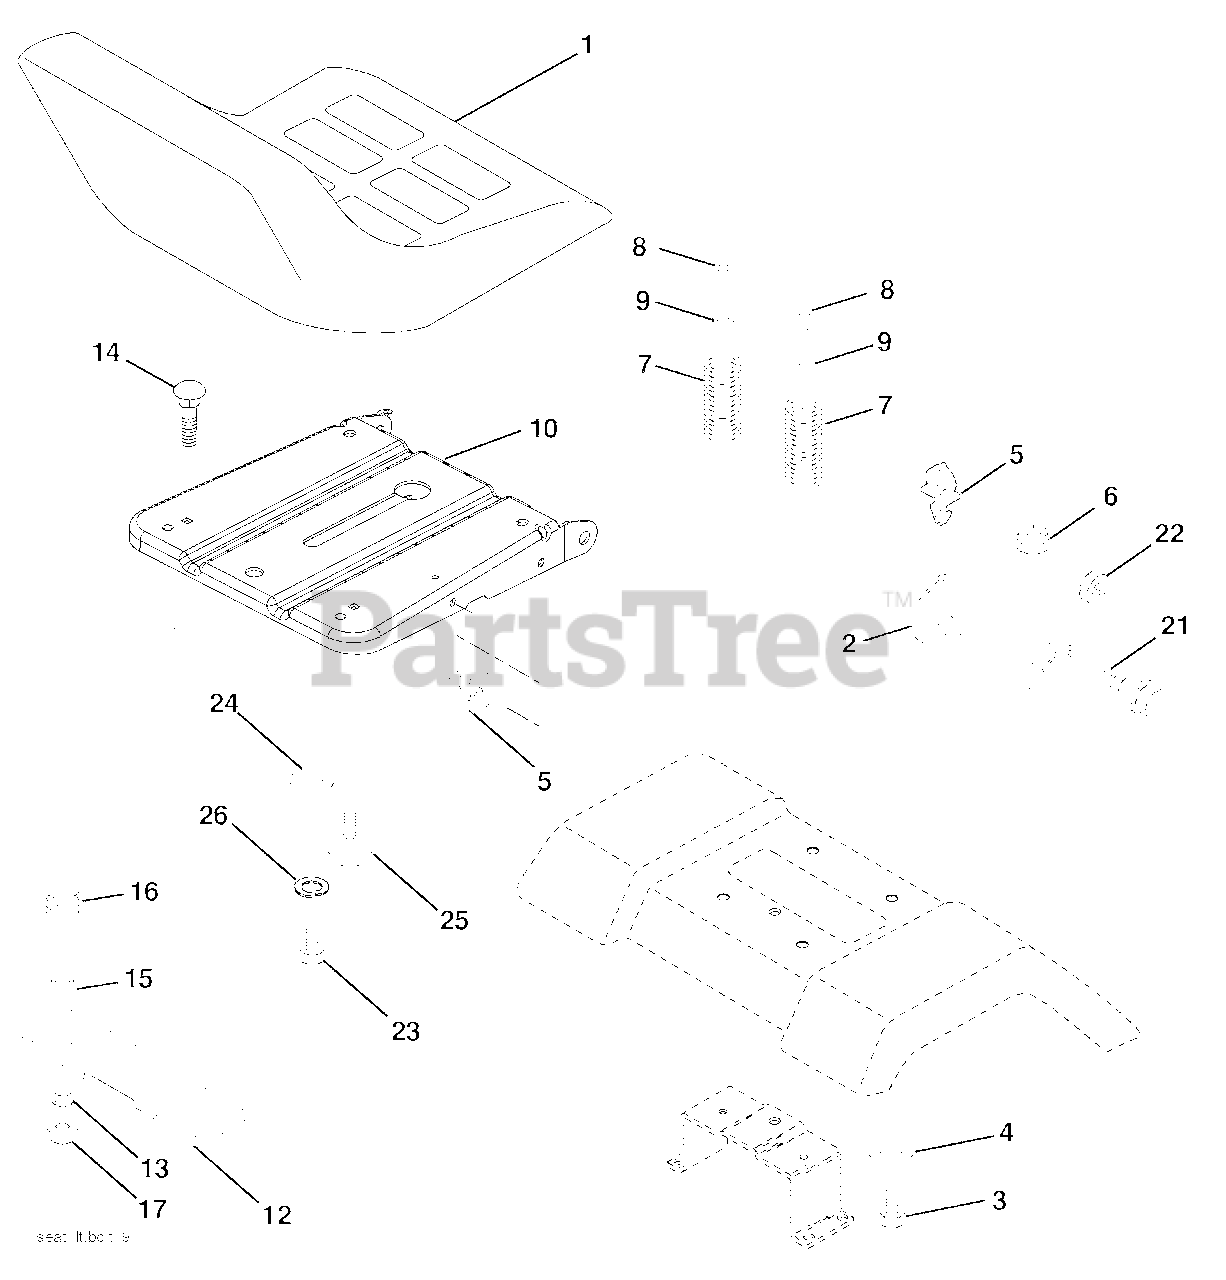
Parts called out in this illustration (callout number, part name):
1	Seat
2	Bracket Seat Pivot
3	Bolt Hex 3/8 - 16 x 1
4	Washer 13/32 x 1 x10 Ga.
5	Clip Push-In Hinged
6	Nut Lock Hex w/Ins 3/8 - 16
7	Spring Seat Cprsn 2 250 Blk Zi
8	Screw 3/8-16 x 1.5
9	Washer 13/32 x 1 x 14 Ga.
10	Pan Pnt Seat
12	Bracket Pnt Mounting Switch
13	Bushing Snap Blk Nyl
14	Bolt Rdhd Sht Nk 1/4 - 20 x 1 -1/2
15	Spacer Split .28 x .96
16	Spring Cprsn
17	Nut Lock 1/4 Lge Flg
21	Bolt Shoul der 5/16-18 unc-2A
22	Nut Lock Hex w/Ins 5/16 - 18
23	Bolt Hex
24	Washer 17/32 x 1-3/16 x 12 Ga.
25	Bolt Shoul der 5/16-18 x .62
26	Washer Lock Hvy Hlcl Spr 1/2
